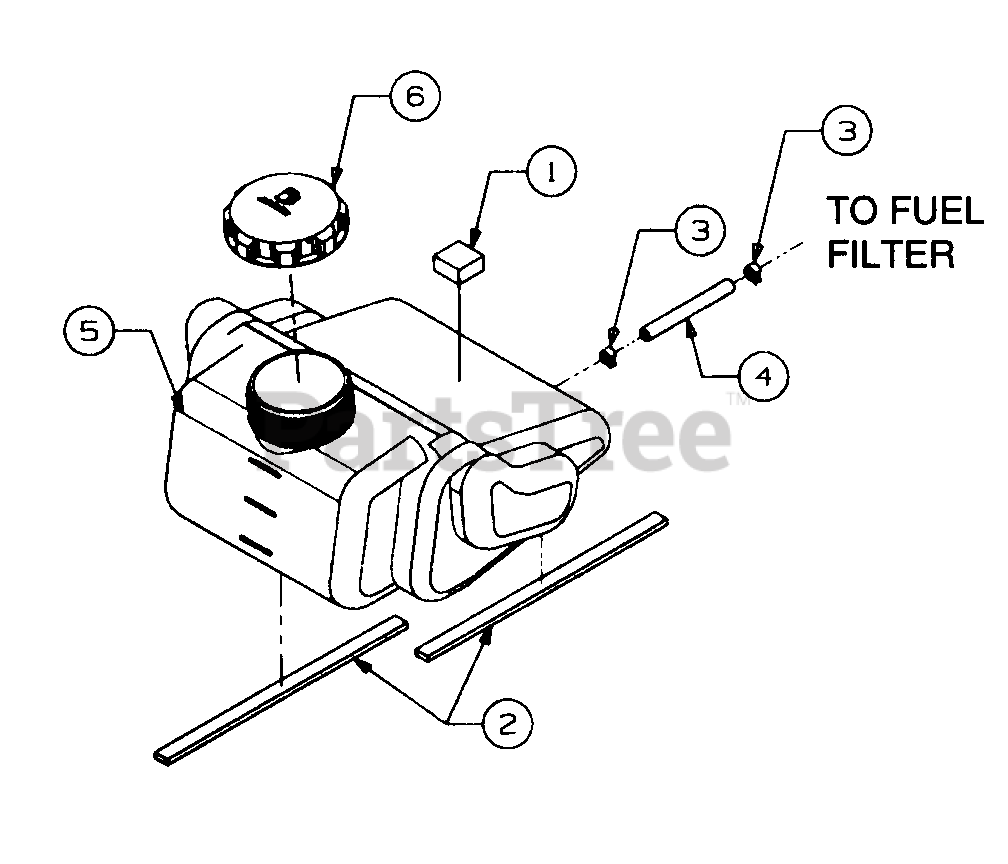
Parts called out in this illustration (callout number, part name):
1	Foam, 1.25 Sq x .62 Thk
2	Tape, Foam, .625 Wide x .25 Thk
3	Clamp, Hose
4	Line, Fuel, 55 in. Lg
5	Tank, Fuel
6	Cap, Fuel
